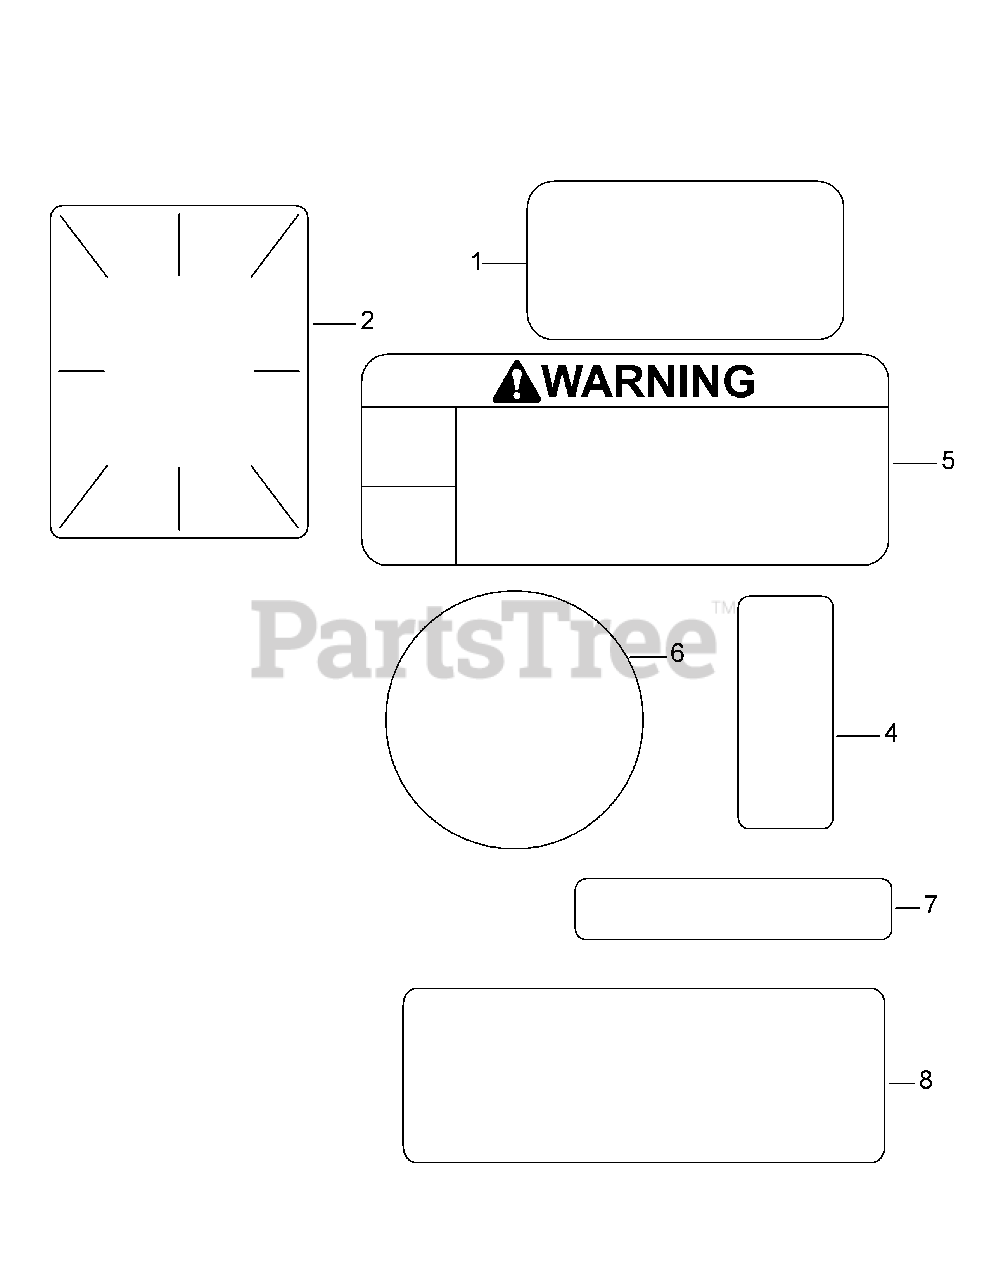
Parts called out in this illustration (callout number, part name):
1	Maintenance Label
2	Clear Laminate Label
4	Fuel Shut Off & Choke Label
5	Warning Label
6	Recoil Label
7	Throttle Label
8	Horsepower Label
